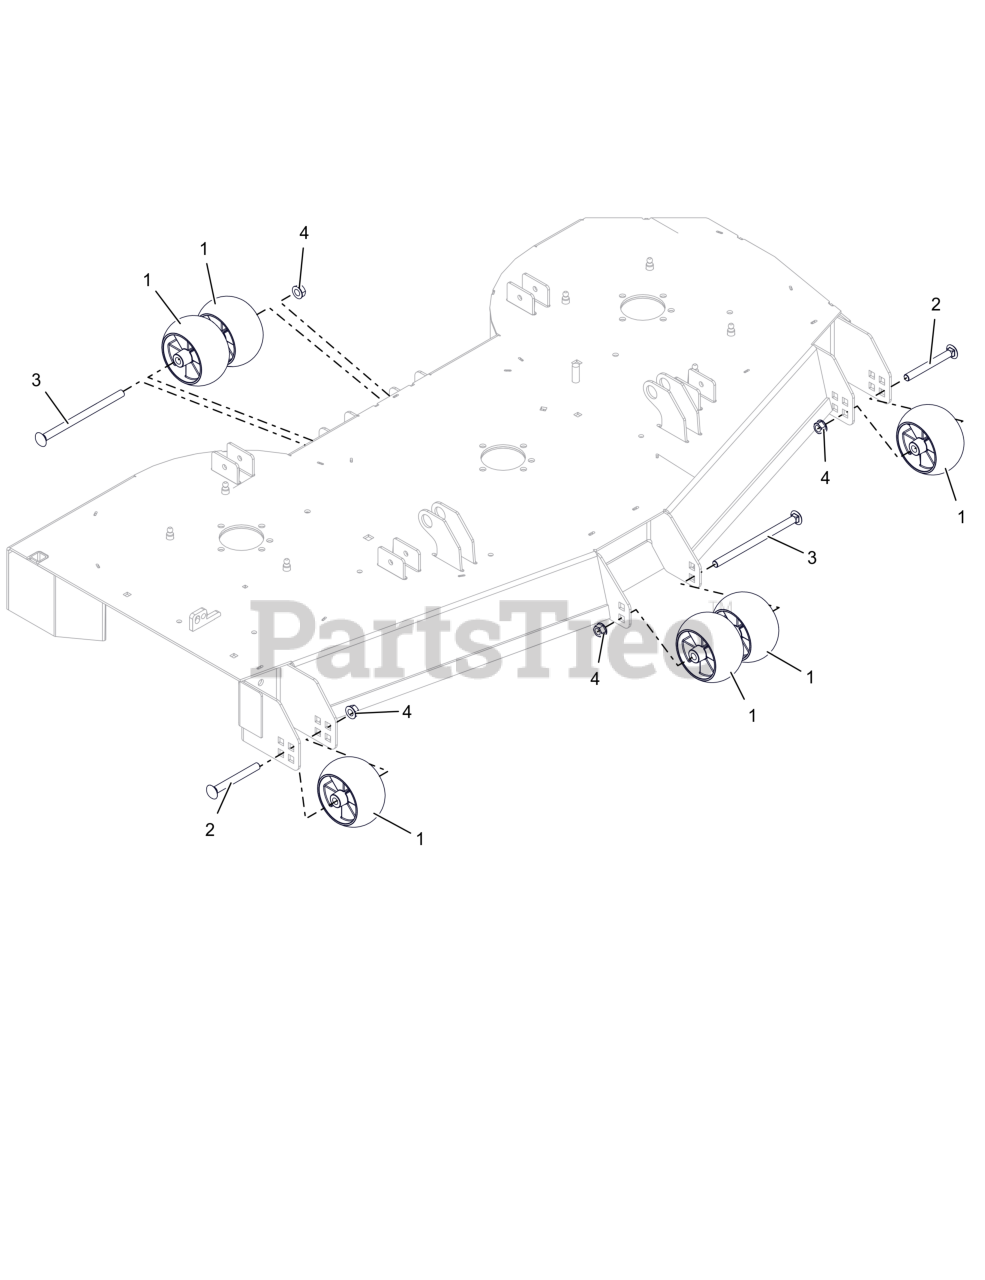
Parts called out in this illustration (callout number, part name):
1	WHEEL, ANTI SCALP - 5X3 CTR W/RIBS
2	BOLT, RHNS .50-13X4.50 G5 ZCC NS
3	BOLT, RHNS .50-13X8.00 G5 ZCC NS
4	NUT-LK-CTR-FLG .500-13 GG ZCC
